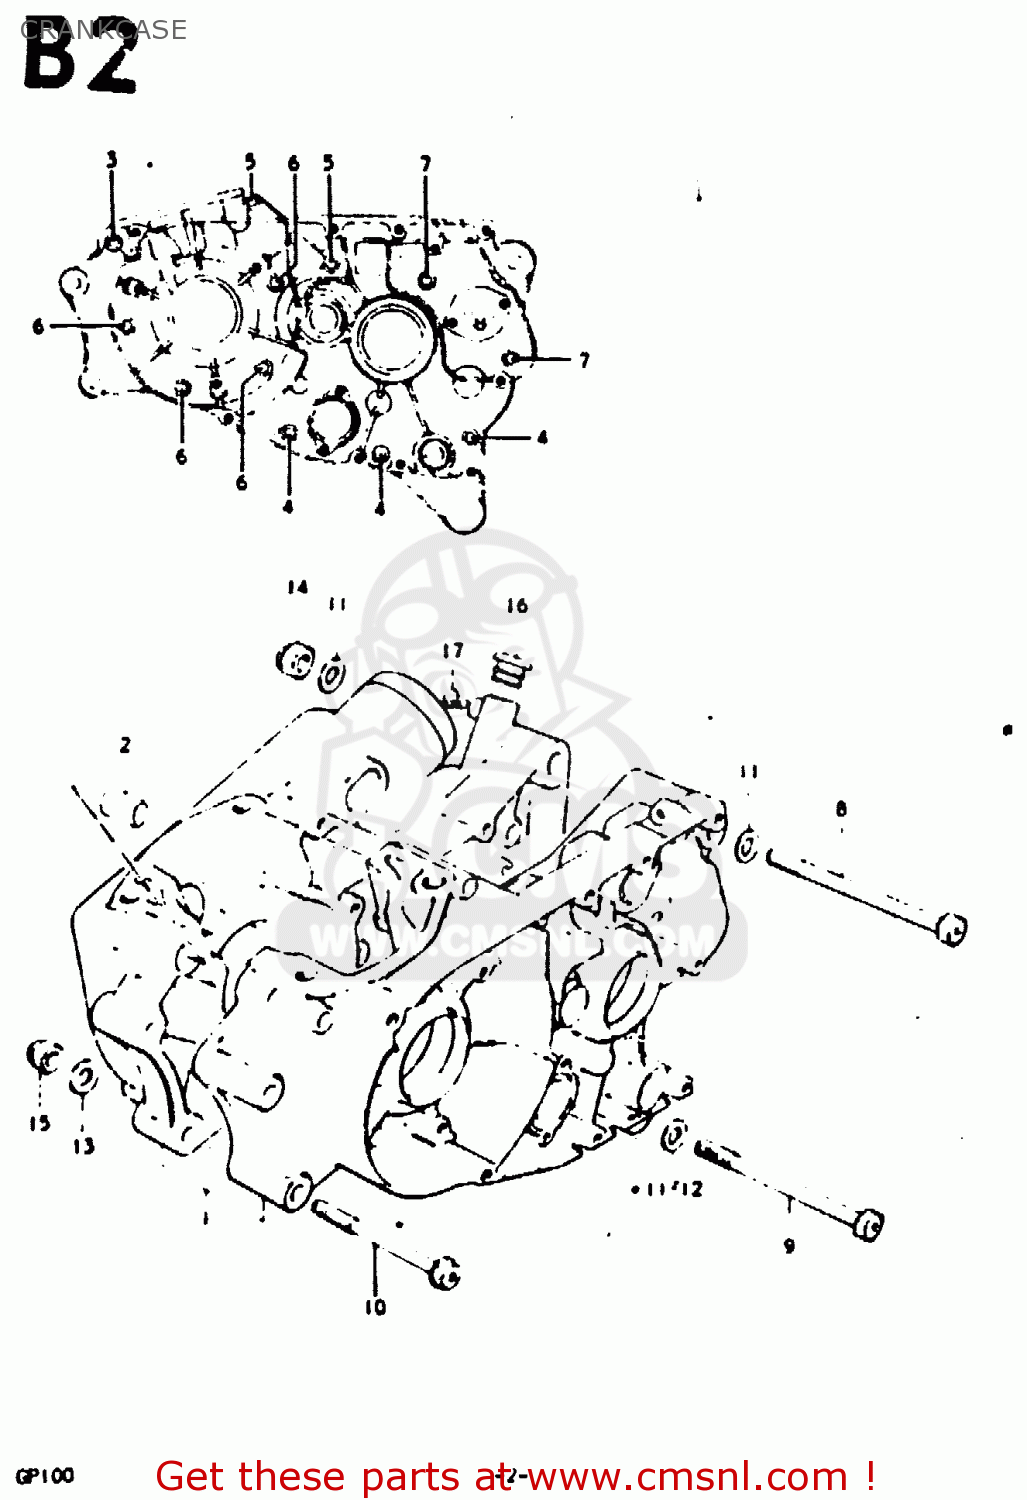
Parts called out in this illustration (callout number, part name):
1	CRANKCASE SET
2	PIN
3	SCREW 6X70
4	SCREW 6X65
5	SCREW
6	SCREW
7	SCREW (6X35)
8	BOLT 10X120
9	BOLT(10X110)
10	BOLT
11	WASHER
13	WASHER
14	NUT
15	NUT
